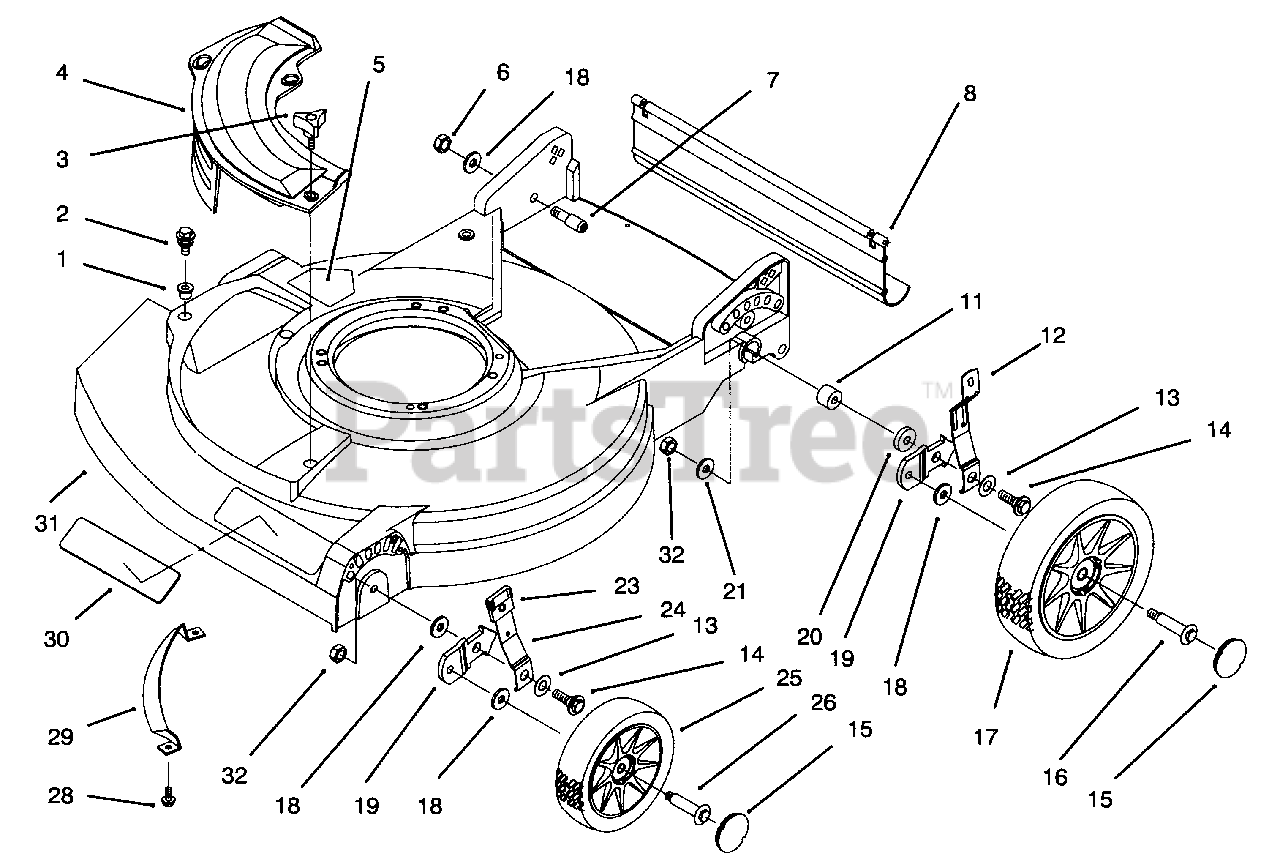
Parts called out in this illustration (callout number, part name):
1	Grommet
2	Screw-Thread Forming
3	Knob
4	Cover-Plate, Mulch
5	Decal-Danger (English)
5	Decal-Danger (French /English)
7	Bolt-Shoulder
8	Shield-Trailing
12	Spring Arm Assembly
13	Washer-Belleville
14	Bolt-Shoulder
16	Bolt-Wheel
17	Wheel Assembly 8"
18	Washer-Wheel Bolt
19	Bracket-H.O.C.
20	Washer
23	Knob-Spring Arm
24	Spring Arm Assembly
25	Wheel-6"
26	Bolt-Wheel
29	Bar-Toe
30	Applique
31	Housing-21" (Incl. Ref.#5 & 30)
32	Nut-Lock
